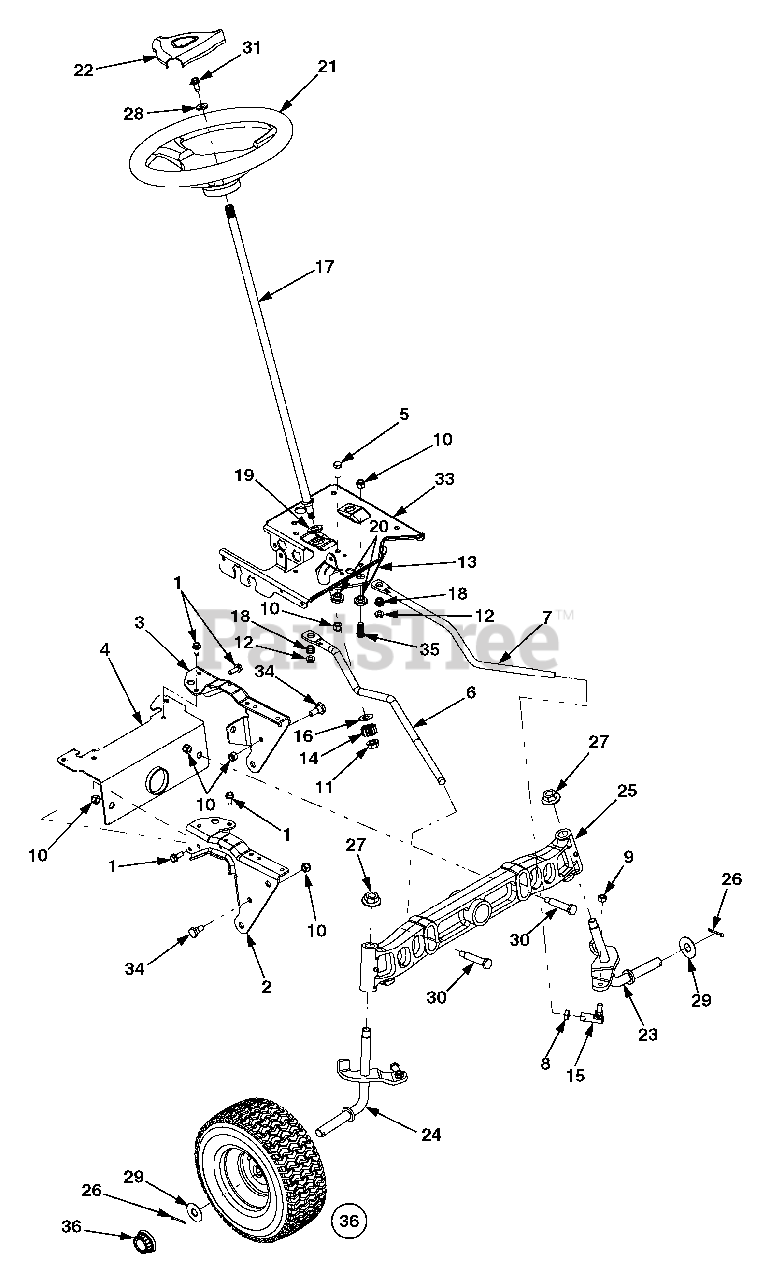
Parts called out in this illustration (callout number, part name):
1	Hex Wash. Hd. Tapp Screw, 5/16-12 x .75
5	Hex Cap Screw, 3/8-16 x 1 (GR 5)
6	RH Drag Link
7	LH Drag Link
8	Jam Nut, 7/16-20 (Grade 2)
9	Hex Center Lock Nut, 3/8-24 (GR 2)
10	Hex Insert Lock Nut, 3/8-16
11	Flange Lock Nut, 7/16-20
12	Flange Lock Nut, 5/16-18
13	Steering Gear, 11/90 Ratio
14	Steering Pinion Gear
15	Ball Joint, 7/16-20
16	Flat Washer, .51 x 1.12 x .06
17	Steering Shaft, .625 OD x 25
18	Plastic Bushing, .38 ID
19	Hex Flange Bearing, 5/8
20	Shoulder Spacer, .38 ID
21	Steering Wheel, Soft Grip
22	Steering Wheel Cap
26	Cotter Pin
27	Nut, Hex Flanged 5/8-18
28	Flat Washer, .406 x .875 x .105
29	Flat Washer, .755 x 1.92 x .06
30	Shoulder Screw, .5 x 2.2, 3/8-16
31	Hex Wash. Hd. Tapp Screw, 5/16-18 x .75
33	Steering Support Bracket
34	Shoulder Screw, 3/8-16
35	Hex Bolt 3/8-16 x 1.0 Special
36	Hubcap
36	Tire Only
